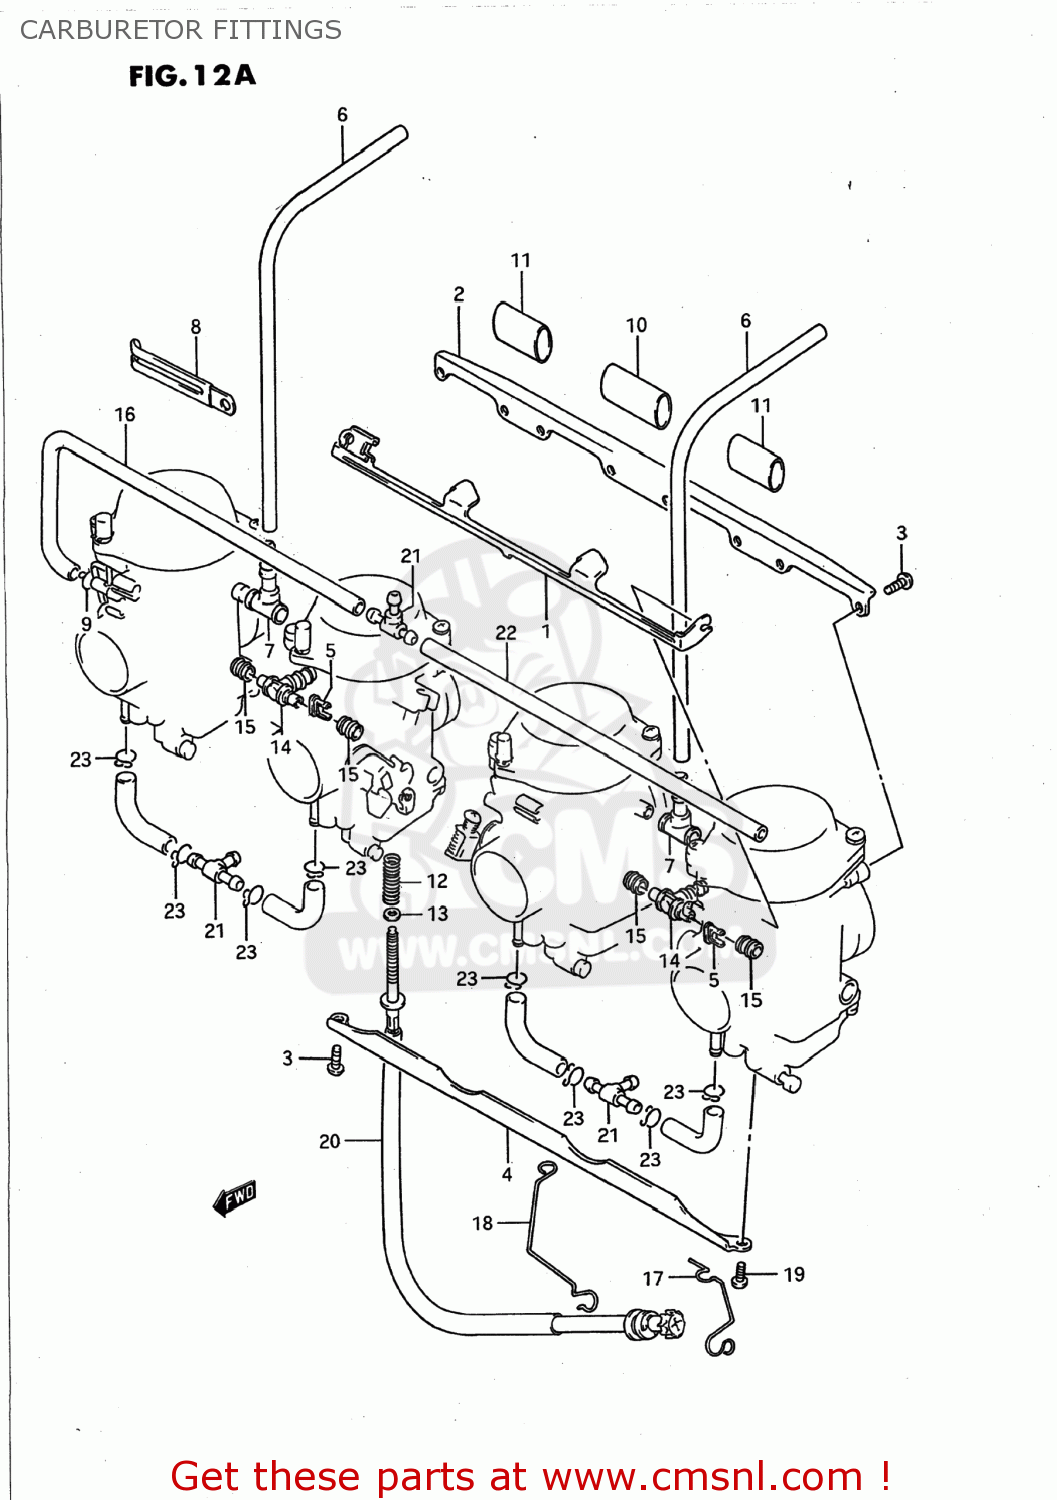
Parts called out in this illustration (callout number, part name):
1	LEVER
2	PLATE
3	SCREW
4	PLATE
5	HOLDER
6	HOSE
7	HOSE
8	CLIP
9	CLIP
10	HOSE
11	HOSE
12	SPRING
13	WASHER
14	NIPPLE
15	SEAL
16	HOSE
17	CLIP
18	CLIP
19	SCREW
20	ADJUSTER
21	NIPPLE
22	HOSE
23	CLIP
